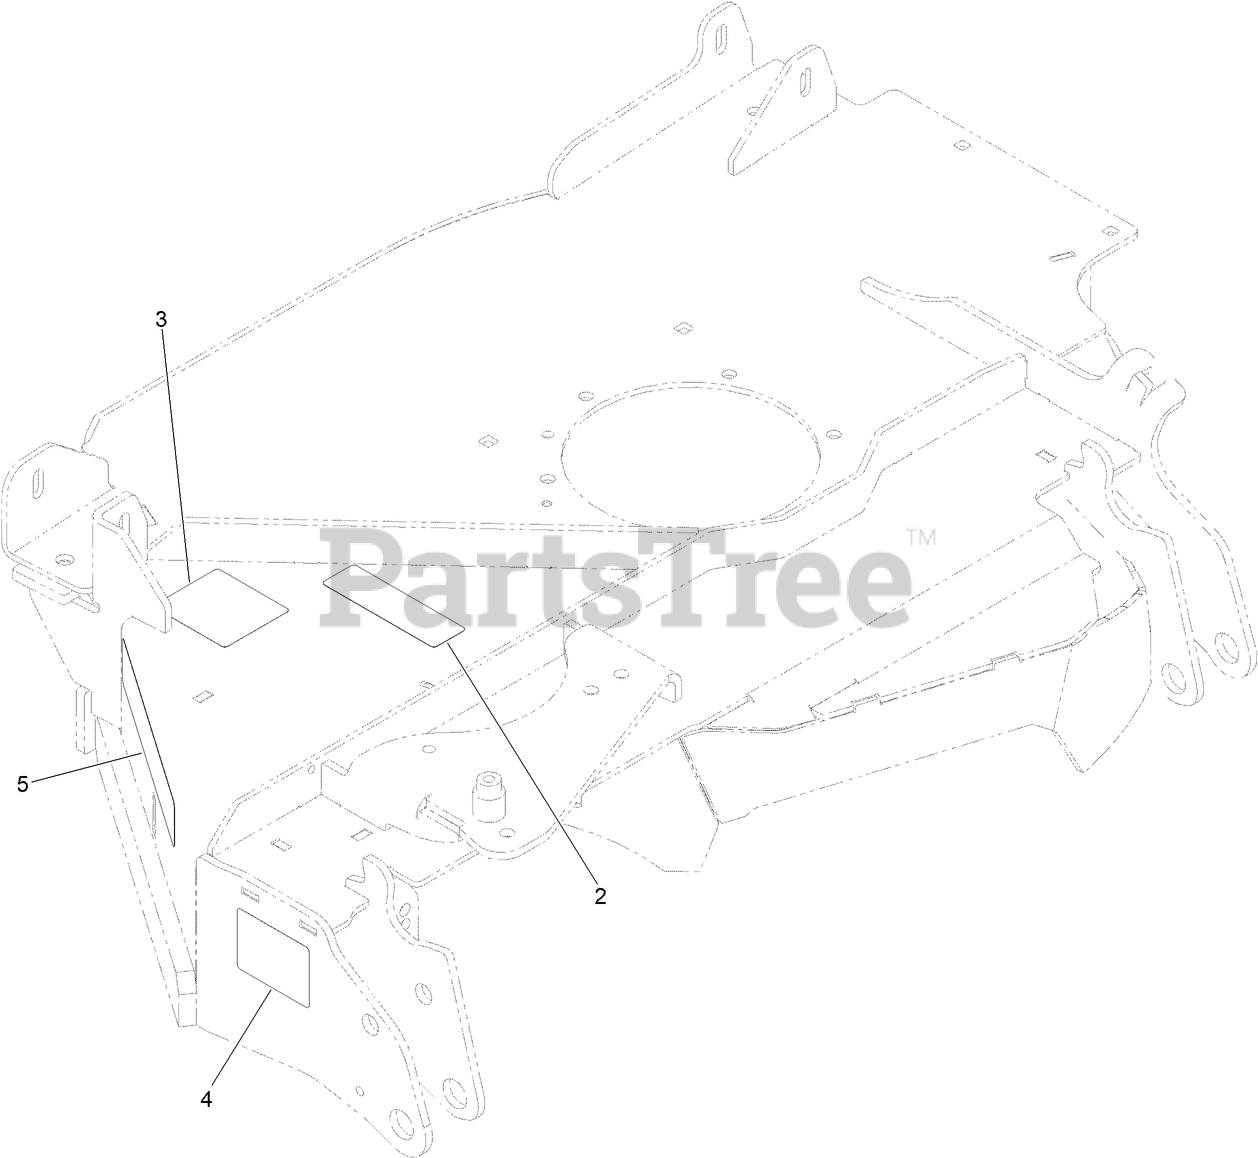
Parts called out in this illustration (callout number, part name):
2	DECAL-COVER, MISSING
3	DECAL-DANGER, THROWN OBJECT
4	DECAL-WARNING, PINCH POINT
